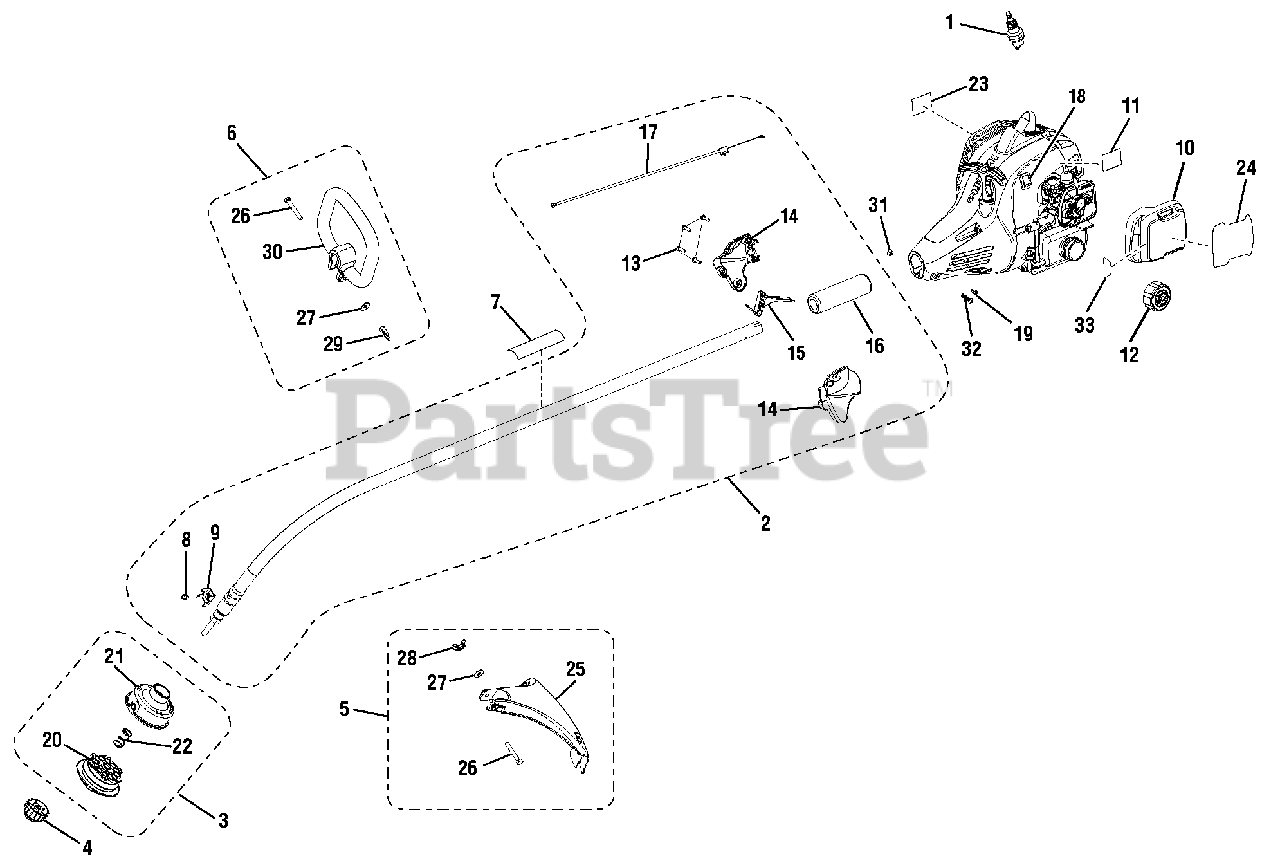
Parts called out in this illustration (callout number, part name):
1	Spark Plug (Champion RCJ6Y)
2	Boom Assembly
3	String Head Assembly
4	Spool Retainer
5	Grass Deflector Assembly
6	Front Handle Assembly
7	Icon Warning Label
8	Screw (10-32 x 3/8 in.)
10	Air Box Cover
11	Model Label (26CS)
13	Screw (M4 x 20 mm)
14	Handle Assembly
15	Throttle Trigger
16	Foam Grip
17	Throttle Cable
18	Switch
19	Screw (8-16 x 5/16 in.)
20	Spool
21	String Head Housing
22	Spring
23	Combustion Warning Label
24	Starting Label
25	Grass Deflector
26	Bolt (1/4-20 x 2 in.)
28	Wing Nut (1/4-20)
29	Wing Nut (1/4-20)
30	Front Handle
31	Hex Nut (M6)
32	Screw (M6 x 20 mm)
33	Throttle Label
